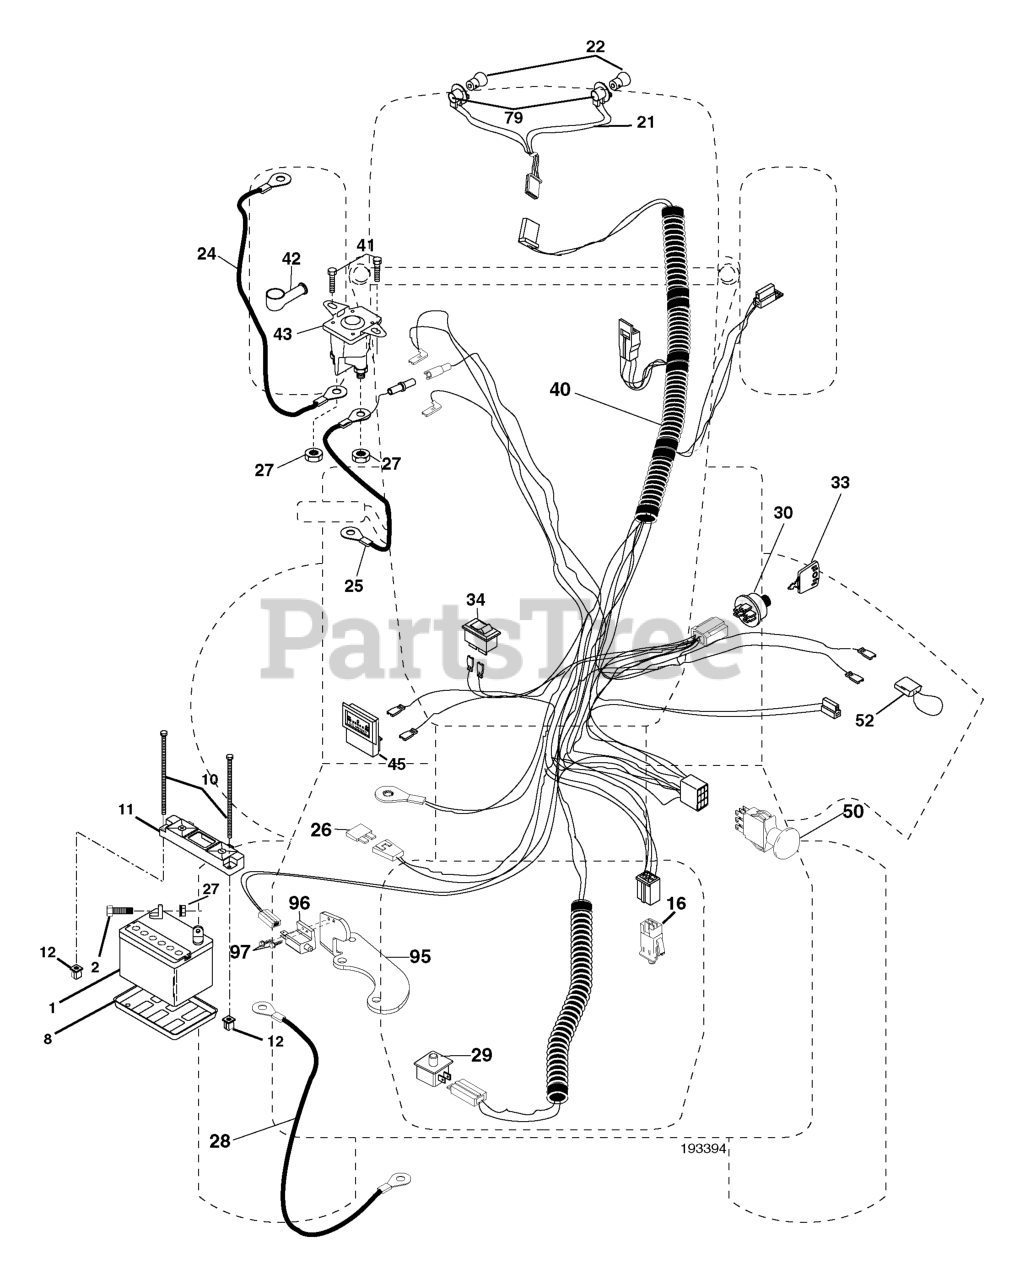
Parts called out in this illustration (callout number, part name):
1	BATTERY 12V .35 AMP
2	BOLT.HEX.1/4.X.3/4.DICHROMATE
8	BATTERY TRAY T
10	BOLT 1/4-20 X 7.5
11	BATTERY HOLDDOWN FRONT MOUNT
12	NUT, PUSH NYLON 1/4" BATTERY
16	SWITCH INTERLOOK PUSH-IN
21	HARNESS.W/LIGHT SOCKET
24	CABLE.STARTER.6GA.22"RED
25	CABLE, BATTERY
27	NUT
28	CABLE, GROUND
29	SWITCH.SEAT.DP W/RAMPS
30	SWITCH.IGN.DELTA.W.LGH.ROS
33	KEY MLD GEN DELTA
40	HARNESS.IGN.REG.RECT
41	SCREW
42	TERMINAL COVER
43	SOLENOID
50	RP.SWTICH.PTO.8.TERMINAL
52	WIRE PROTECTION LOOP
79	BULB HOLDER ASM.
95	BRKT.ROS.6SP
96	SWITCH-INTER. GT
97	SCREW.TT.#10-32X.5.3/8.FLANGE
